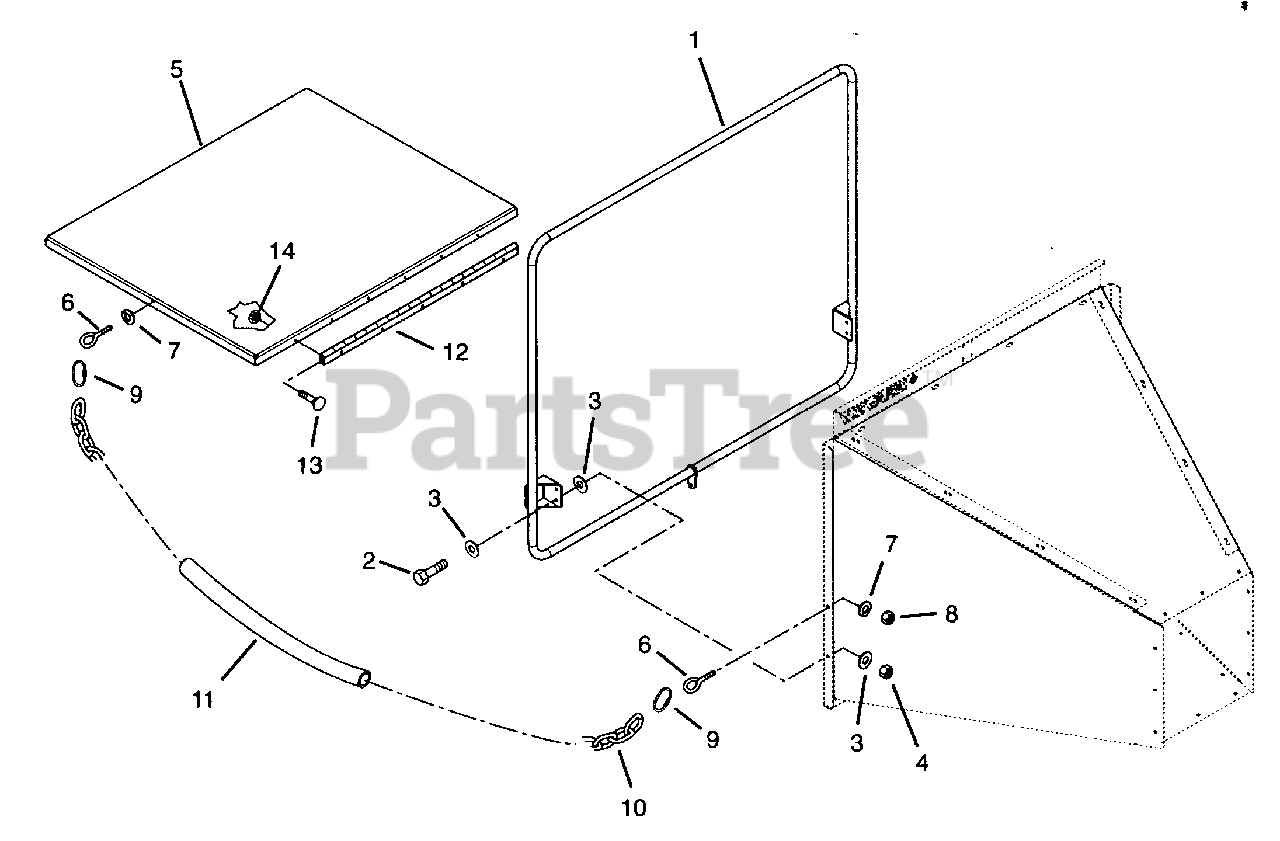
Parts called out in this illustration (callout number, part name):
1	Feed control Bar
2	Bolt-Hex .38-16 x 1.75 Grade 5
3	Washer-Flat-Steel .438 x 1.0 x .083
4	Nut-Locking .375-16
5	Apron Weldment
6	Eye Bolt .375 x 1.25
7	Washer-Lock .375 x .155
8	Nut-Hex .375-16 Grade 2
9	Quick Link 5/16"
10	Apron Chain - 495
11	Vinyl Tubing 1 - 1/2"
13	Bolt-Round Head Square Neck .25-20 x .50
14	Nut-Locking-Center .250-20
